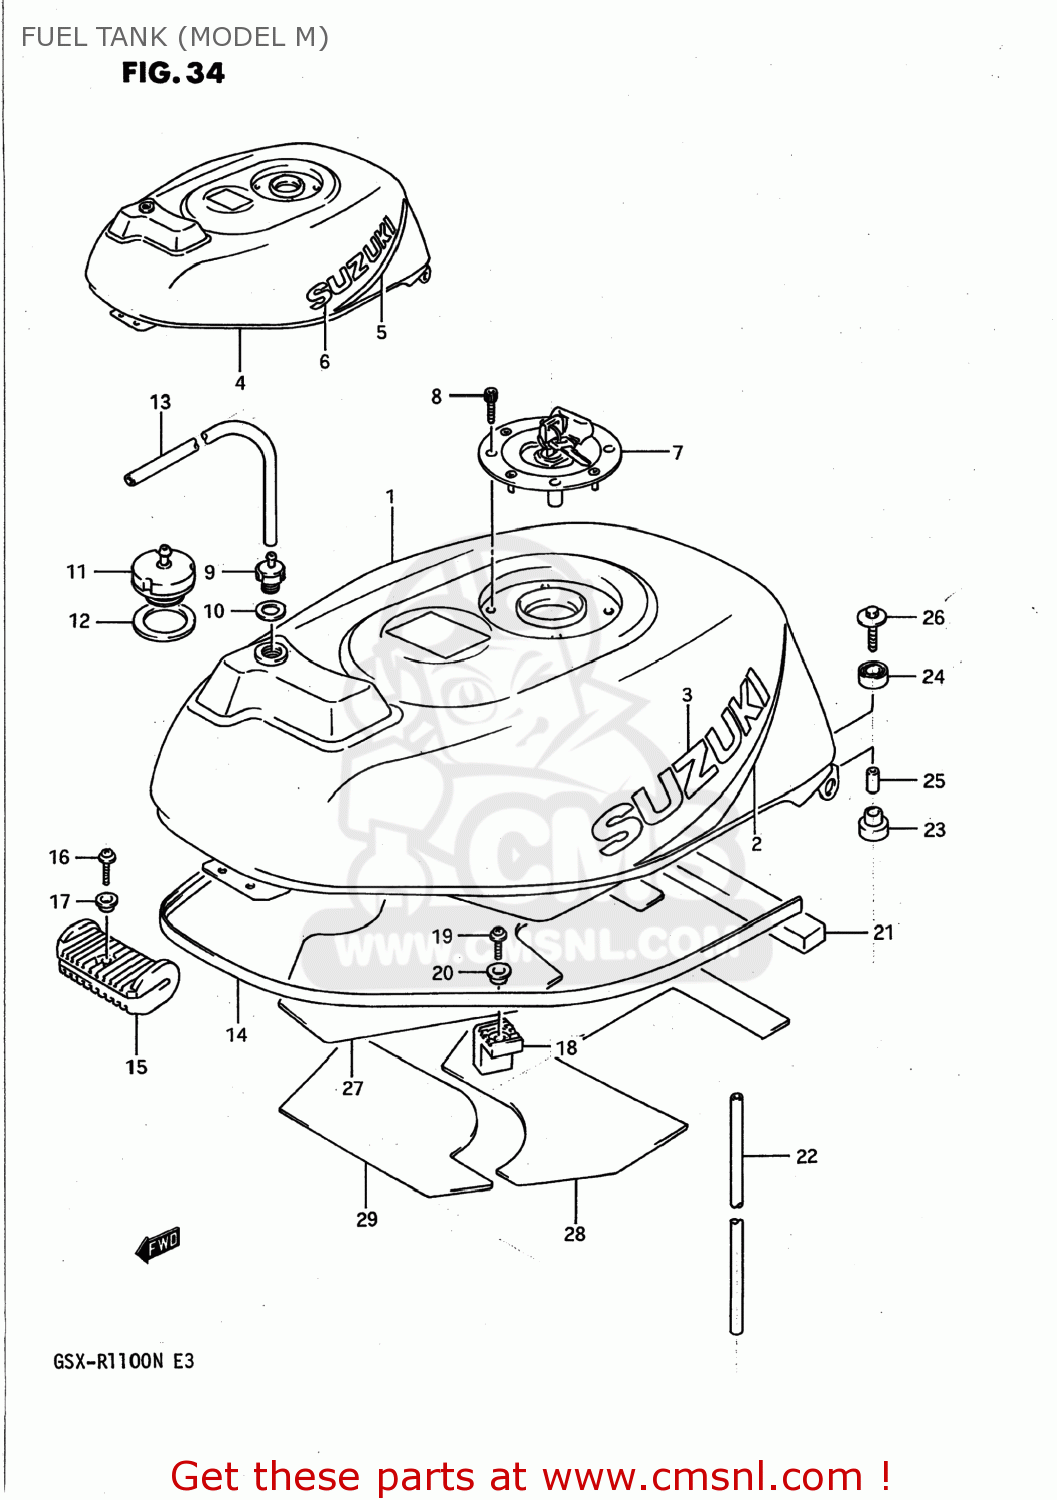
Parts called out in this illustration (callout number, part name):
1	TANK ASSEMBLY,FUEL
2	TAPE SET,FUEL TANK STRIPE
3	EMBLEM,FUEL TANK
4	TANK ASSEMBLY,FUEL
5	TAPE,FUEL TANK
6	EMBLEM,FUEL TANK
7	CAP SET,FUEL TANK
8	BOLT(5X20)
9	PLUG,FUEL TANK BREATHER
10	GASKET(12.5X20X2.5) (NAS)
11	(CA) VALVE,FUEL TANK BREATHER
12	GASKET 27X40X2.5 (NAS)
13	HOSE(5X8.2X600)
14	MOLDING,FUEL TANK
15	CUSHION,FUEL TANK FR
16	SCREW 5X10
17	WASHER
18	CUSHION,FUEL TANK SIDE
19	SCREW
20	WASHER
21	CUSHION, AIR SEAL
22	HOSE
23	CUSHION
24	CUSHION
25	SPACER
26	BOLT(6X35)
27	HEAT SHIELD,FUEL TANK
28	HEAT SHIELD,FUEL TANK IN
29	HEAT SHIELD,FUEL TANK IN
